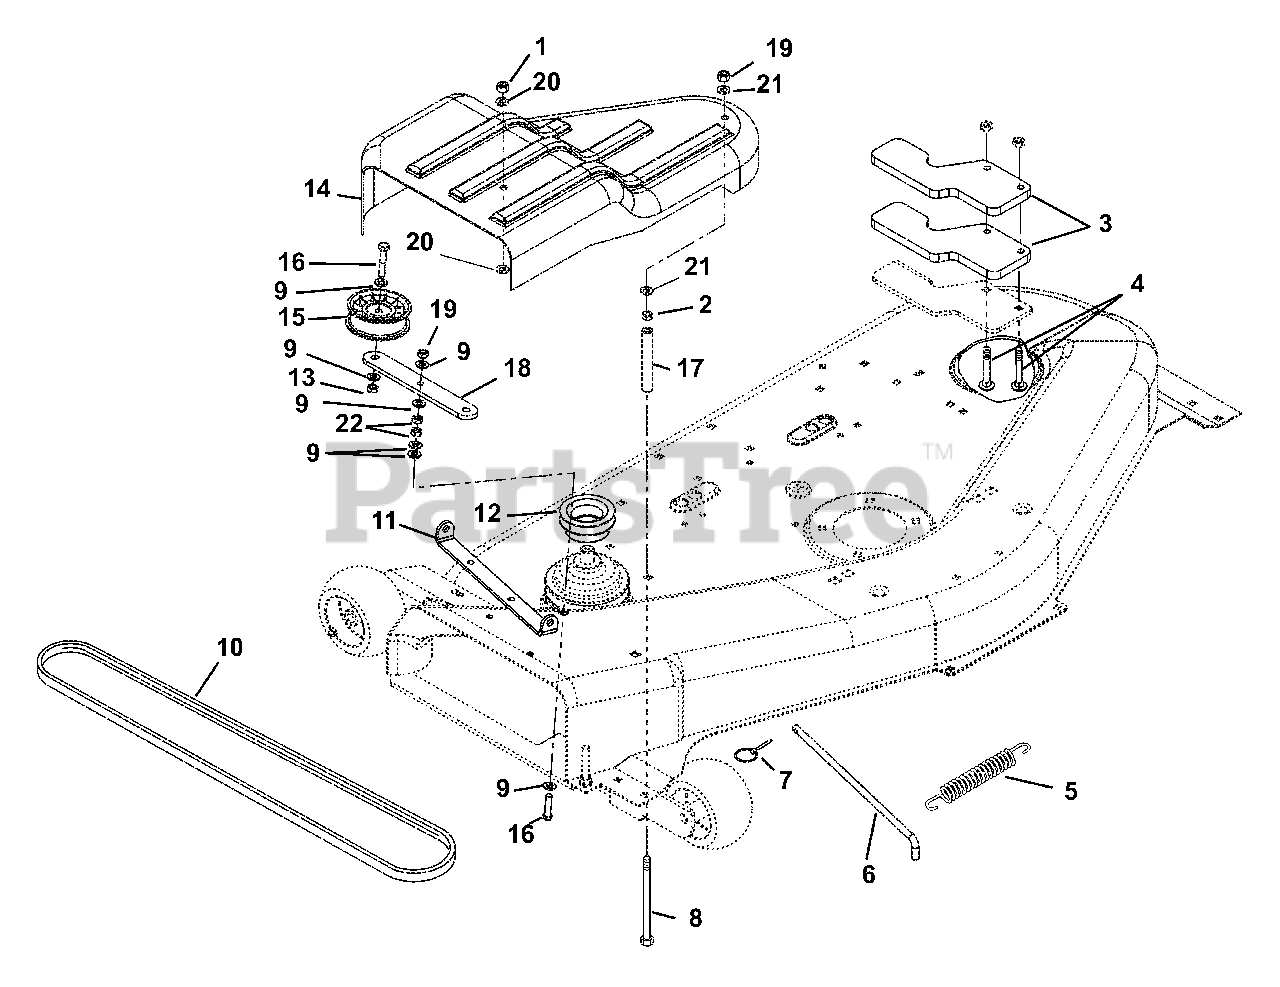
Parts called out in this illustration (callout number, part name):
1	Nut-Lock-Nylon .250-20
2	Nut-Locking-Center .312-18
3	Counterweight
4	Bolt-Round Head Square Neck .31-18 x 1.75 Grade 5
5	Spring-Tension .069 x .62 x 3.50
6	Rod-Mounting
7	Pin-Klik 1.000 x .188 x 1.25
8	Bolt-Hex .31-18 x 6.00 Grade 5
9	Washer-Flat-Steel .344 x .688 x.065
10	V-Belt A-Section 25.95 x .516
11	Bracket-Chute Pivot
12	Pulley-Driver 3.00"
13	Nut-Locking-Flange .31-18
14	Cover, Belt
15	Idler-Flat 3.00 x .38
16	Bolt-Hex .31-18X1.75 Grade 5
17	Spacer-.334 I.D. x 4.63
18	Bracket-Tension Arm
19	Nut-Lock-Nylon .31-18
20	Washer-Flat-Steel .281 x 1.00 x.048
21	Washer-Flat-Steel .344 x 1.375 x 0.75
22	Nut-Jam .31-18
